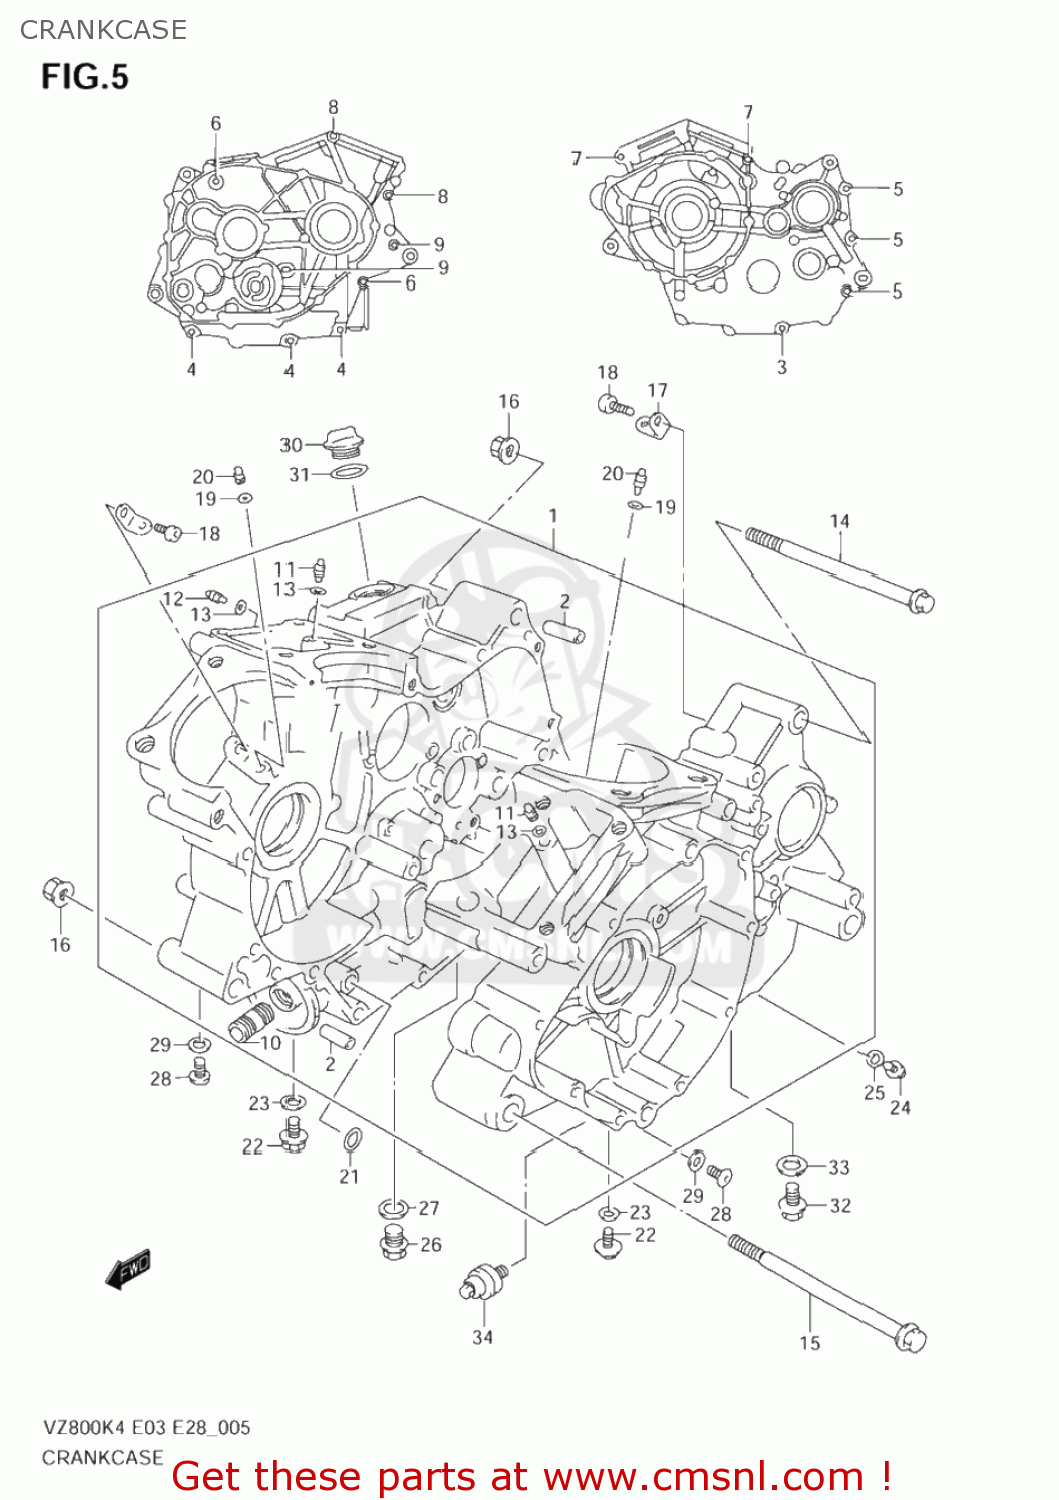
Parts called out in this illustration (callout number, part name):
1	CRANKCASE SET
2	PIN,CRANKCASE
3	BOLT
4	BOLT
5	BOLT
6	BOLT (8X70)
7	BOLT(8X105)
8	BOLT(8X160)
9	BOLT(8X80)
10	UNION,OIL STAND
11	JET,OIL GALLERY(18)
12	JET(8)
13	O RING(D:1.2,ID:4)
14	BOLT(10X143)
15	BOLT(10X155)
16	NUT
17	PLATE,PISTON COOLING JET
18	BOLT(6X12)
19	O RING(D:1.2,ID:4)
20	JET,PISTON COOLING(0.8)
21	O RING(D:1.9,ID:12.6)
22	BOLT
23	GASKET(8.2X16X1) (NAS)
24	BOLT
25	GASKET(5.8X13X1.2) (NAS)
26	PLUG,16X8
27	GASKET(16X22X2) (NAS)
28	BOLT
29	GASKET(8.2X16X1) (NAS)
30	PLUG
31	O RING(D:3.1,ID:16.8)
32	PLUG,12X20
33	GASKET(12.1X16.2X3.7) (NAS)
34	SWITCH ASSY,OIL PRESSURE
